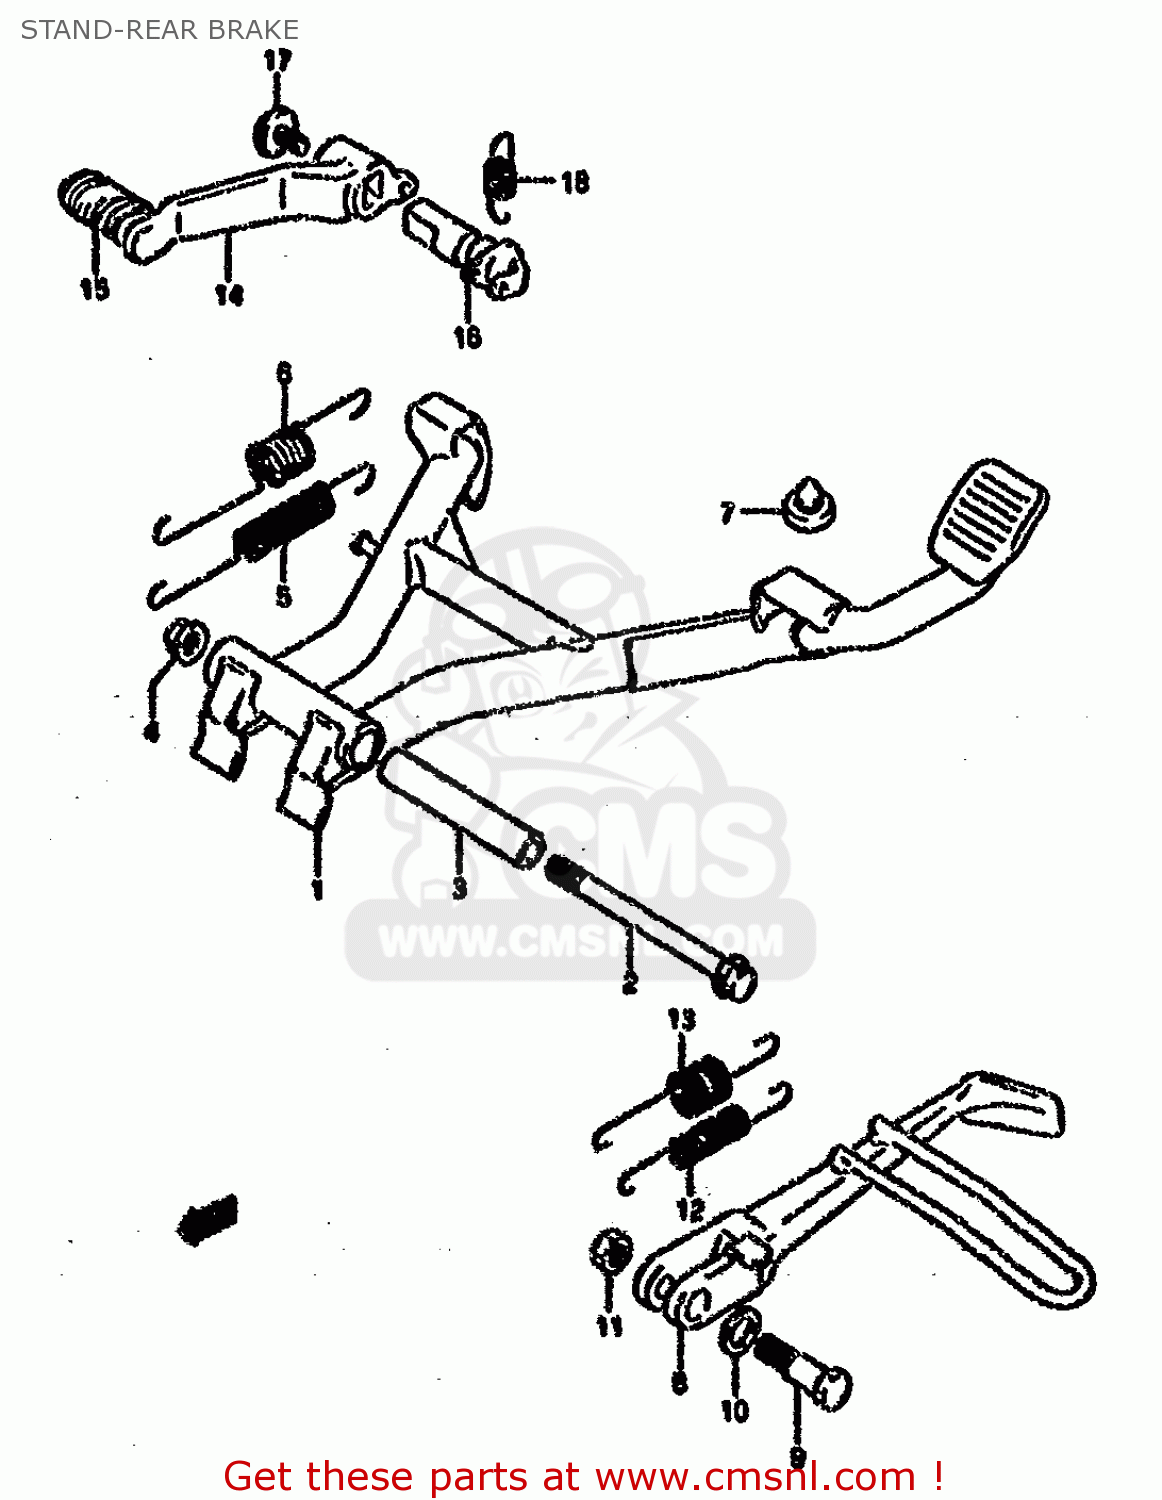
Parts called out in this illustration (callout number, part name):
1	STAND,CTR
2	BOLT(10X115)
3	SPACER,CENTER STAND
4	NUT
5	SPRING,CENTER STAND,INNER
6	SPRING,CENTER STAND,OUTER
7	CUSHION
8	STAND,SIDE
9	BOLT(10X38)
10	SHIM
11	NUT
12	SPRING,PROP STAND,INNER
13	SPRING
14	PEDAL,BRAKE
15	RUBBER,PEDAL
16	ARM,BRAKE PEDAL
17	BOLT(8X14)
18	SPRING,BRAKE PEDAL
